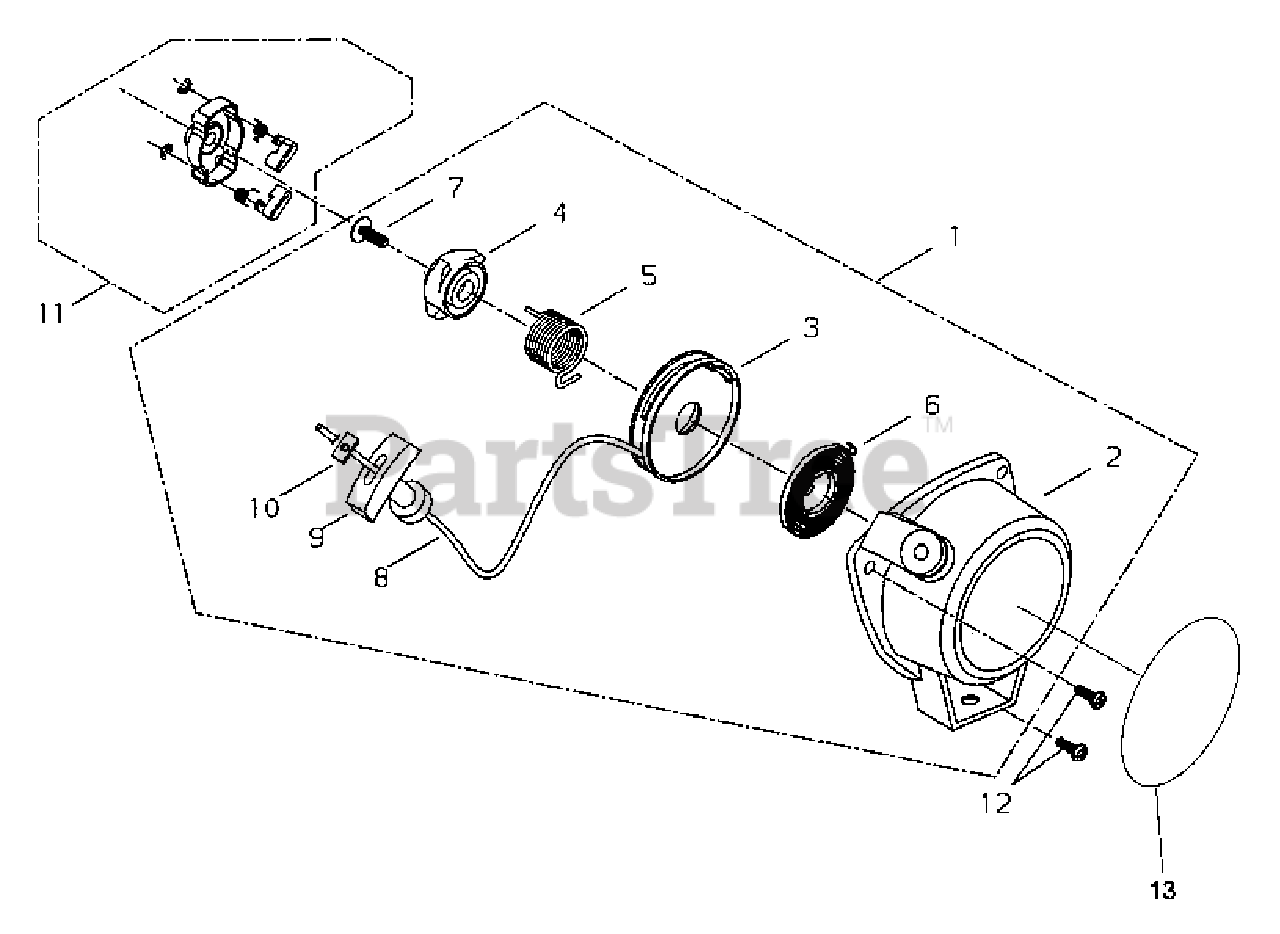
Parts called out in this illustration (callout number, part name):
1	STARTER ASSY
2	CASE, STARTER
3	REEL, ROPE
4	CAM
5	SPRING
6	SPRING, REWIND
7	SCREW - 5
8	ROPE, STARTER
9	GRIP, STARTER
10	RETAINER, ROPE
11	STARTER PAWL ASSY
13	LABEL - STARTER
